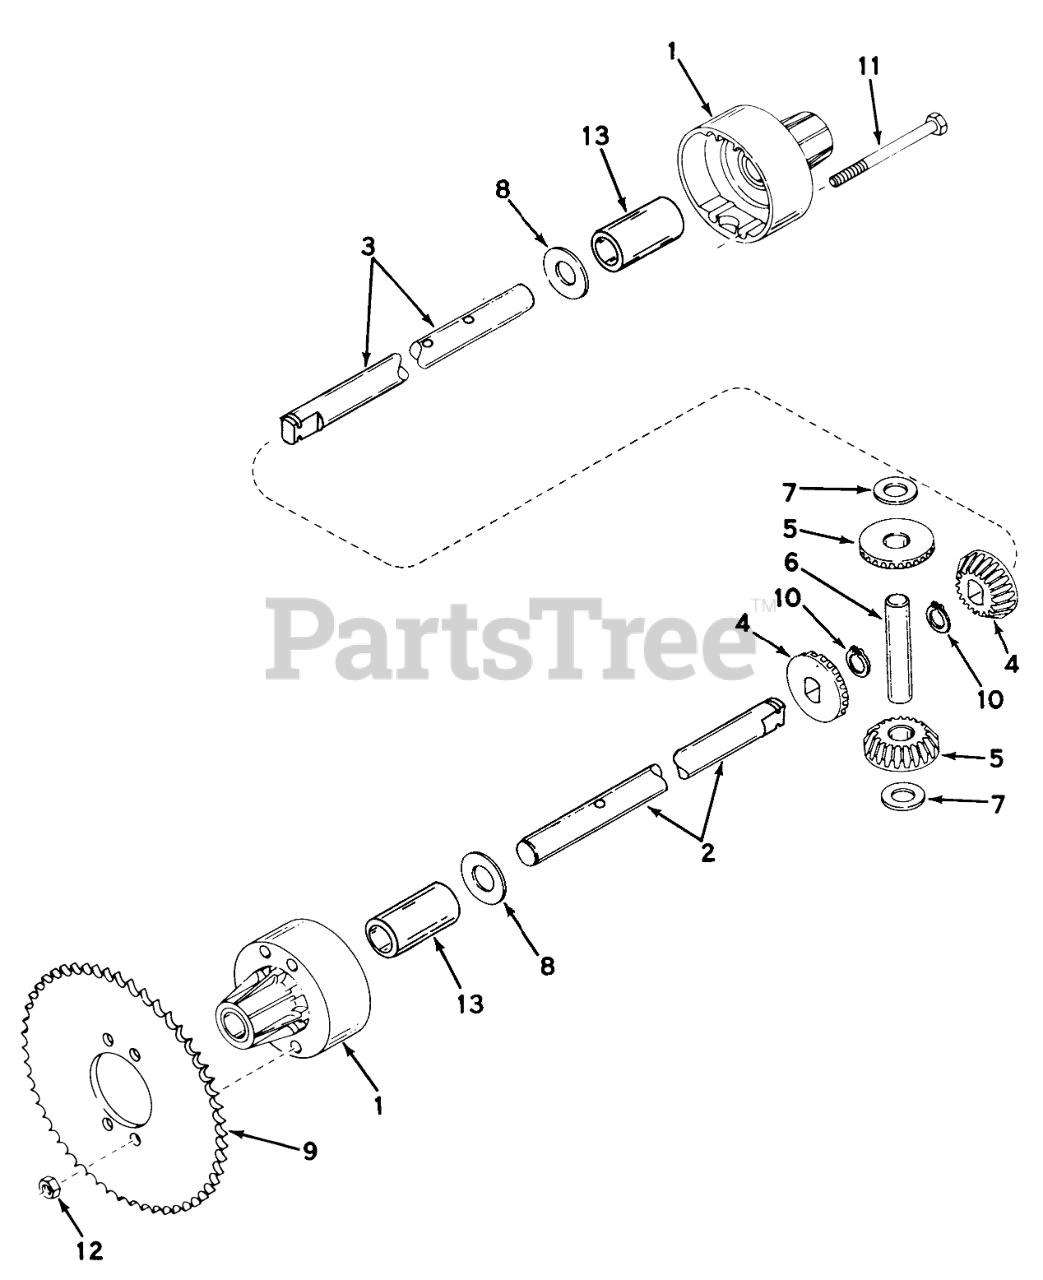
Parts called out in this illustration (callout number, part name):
1	Housing, Differential carrier (Incl. No. 13)
2	Axle (827/32" long)
3	Axle (13 23/32" long)
4	Bevel Gear
5	Gear Pinion
6	Pin Drive
7	Washer, Thrust
8	Washer
9	Sprocket (40 teeth)
10	Snap Ring
11	Screw-Hex Hd.
12	Nut-Lock
13	Bushing
